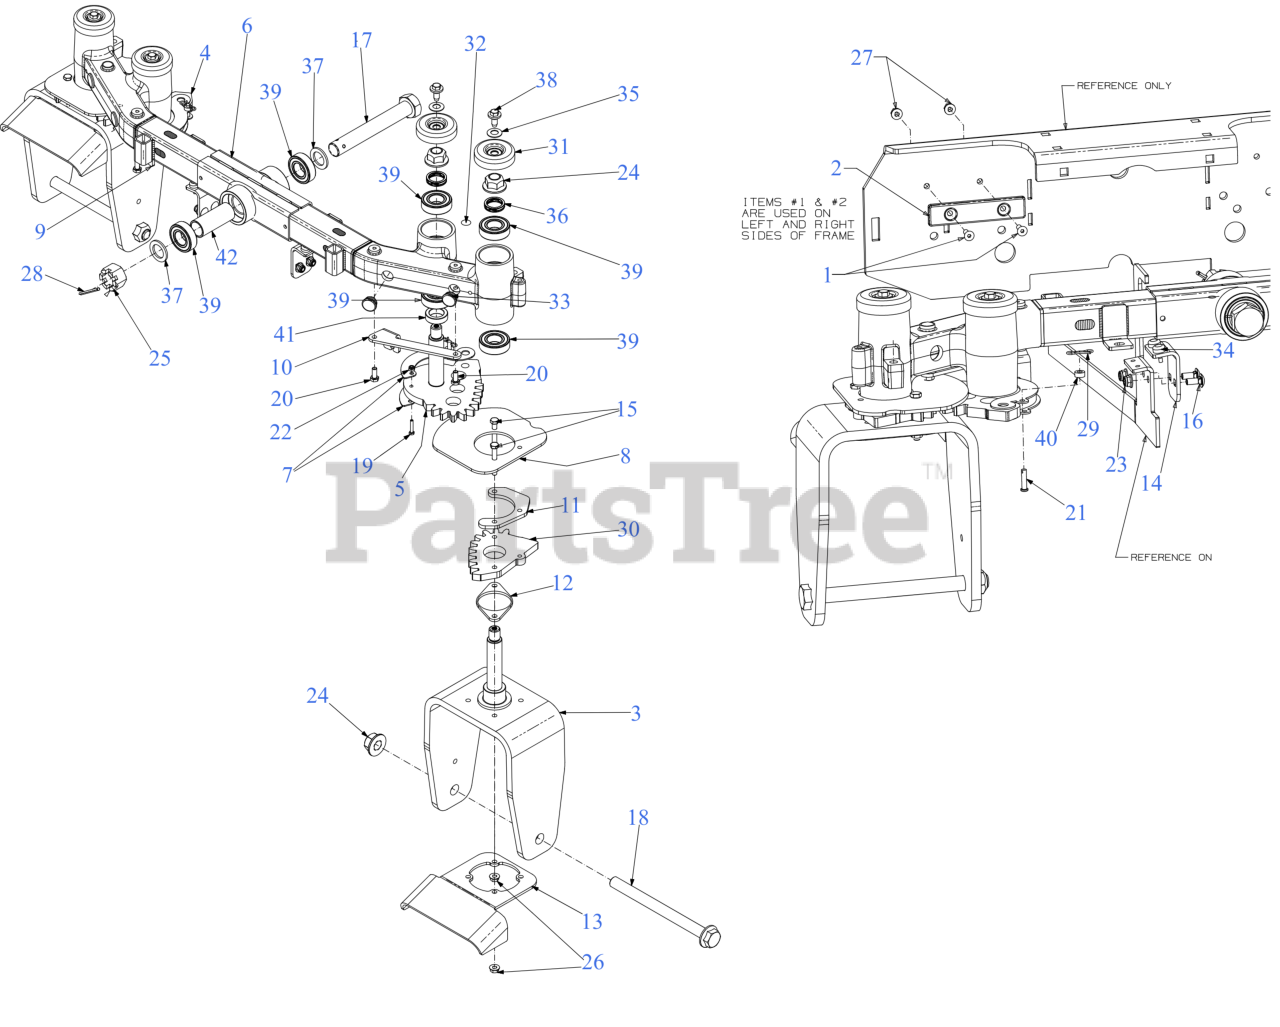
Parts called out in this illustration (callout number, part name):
1	SCREW-FLAT HEAD CA
2	PLATE-LIFT WEAR
5	RIGHT HAND STEERING GEAR ASSEMBLY
6	AXLE ASSEMBLY
12	LOWER GEAR SPACER PLATE
14	AXLE BRACKET
15	HEX SCREW 5/16-18 x 2.25 GR5
16	CARRIAGE BOLT 5/16-18 x .75
17	HEX HEAD SCREW (1-14 x 7 GR5)
18	SCREW 3/4-16 x 9.00 GR5
19	SCREW #10-24 x 1.00 GR5.1
20	SCREW 5/16-18 x .750
21	CLEVIS PIN .25 x 1.00
23	FLANGE LOCK NUT 5/16-18
24	FLANGE LOCK NUT 3/4-16 TOP LOCK
25	CASTLE NUT 1.0-14 GR5
26	HEX FLANGE NUT
27	LOCK NUT 1/4
28	COTTER PIN
29	BOW TIE COTTER PIN 1/4-5/16
30	STEERING GEAR YOKE
31	AXLE CAP 2.5"
32	RATCHET CLIP
34	BUMPER, .62 DIA x .3
35	BELL WASHER
36	WAVE WASHER
37	FLAT WASHER 1.005 x 1.570 x 0.125
39	BALL BEARING (1.0 x 52 x 15)
42	SPACER 1.00 x 1.25 x 2.99
